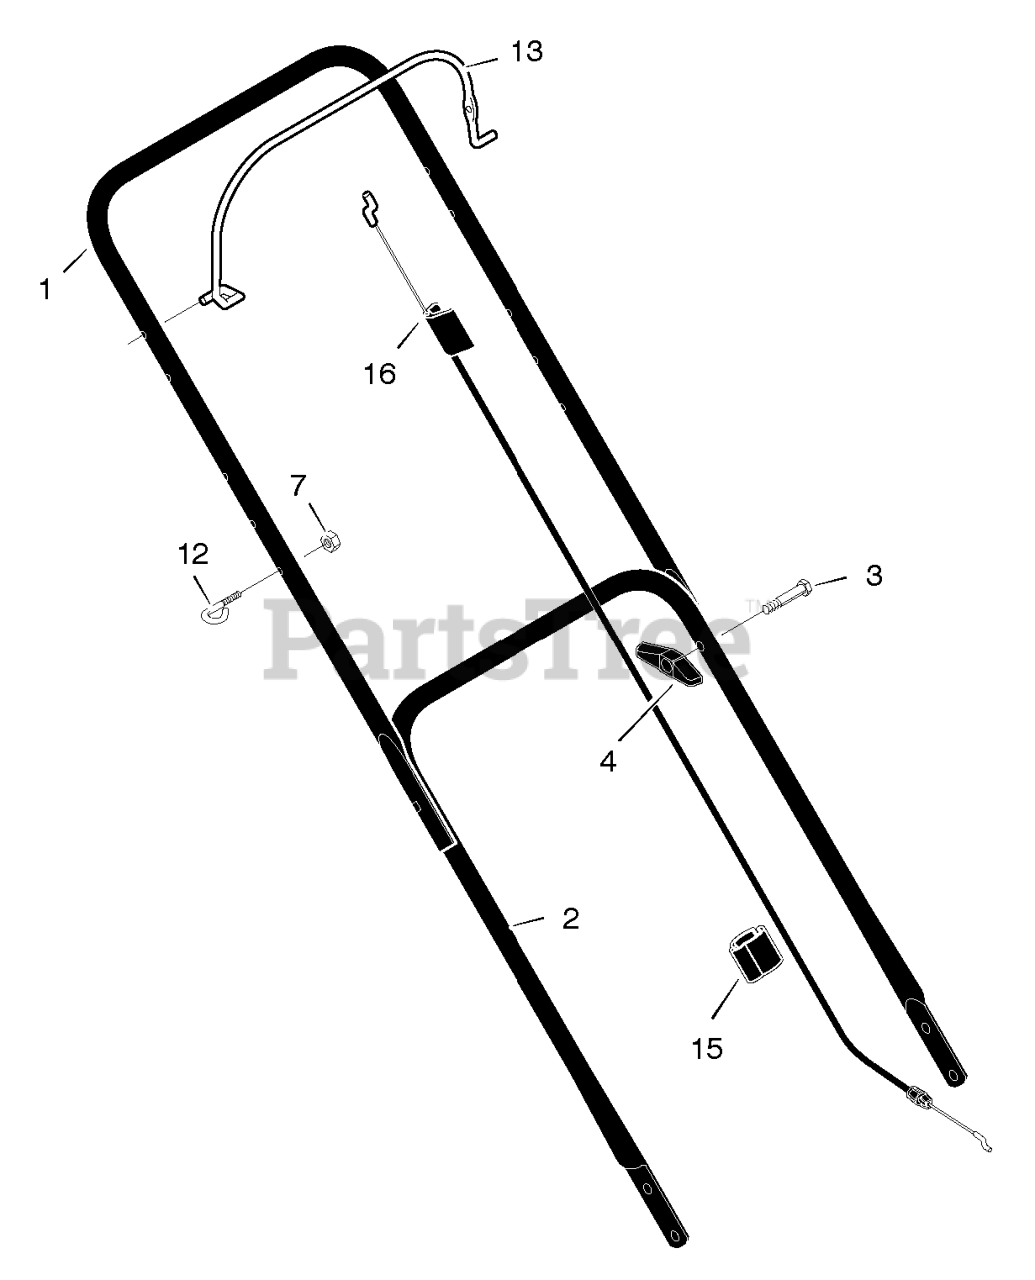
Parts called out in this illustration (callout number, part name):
1	Handle, Upper (Black)
2	Handle, Lower (Black)
4	Knob, Plastic
7	Locknut
12	Guide, Rope
13	Lever, Engine Stop
15	Clip, Cable
16	Engine Stop Cable
